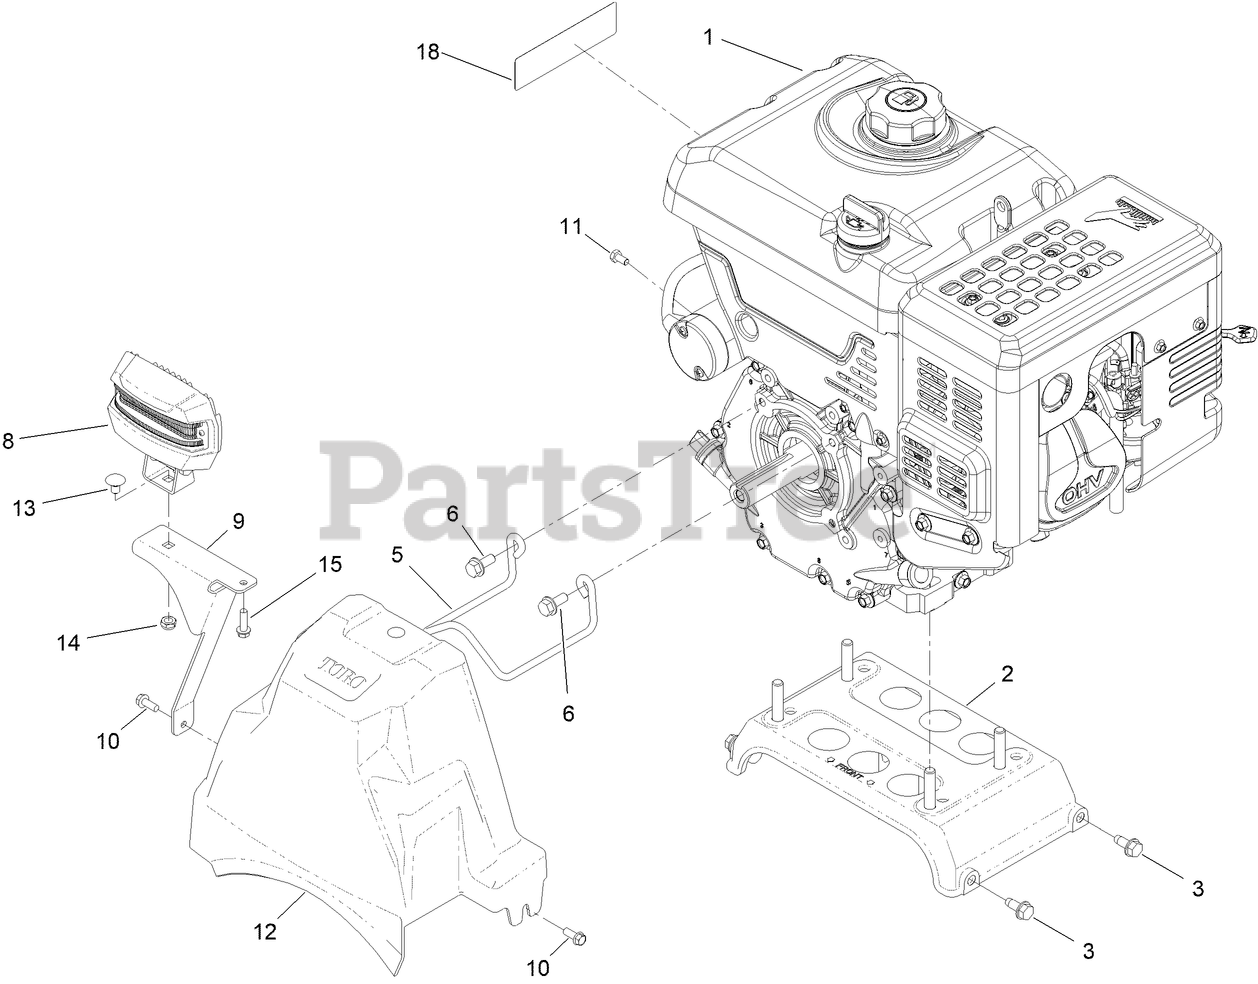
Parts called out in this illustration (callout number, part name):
1	ENGINE-LC190FDS
2	ENGINE PLATE ASM
3	SCREW-HWHTF
5	BELT GUIDE
6	SCREW-HH
8	LED LIGHT ASM
9	BRACKET-LIGHT
10	SCREW-HWH
11	SCREW-HH
12	COVER-BELT
13	BOLT-CARR
14	NUT-HEX
15	SCREW-PLASTITE, HWH
18	DECAL - 420CC OHV
